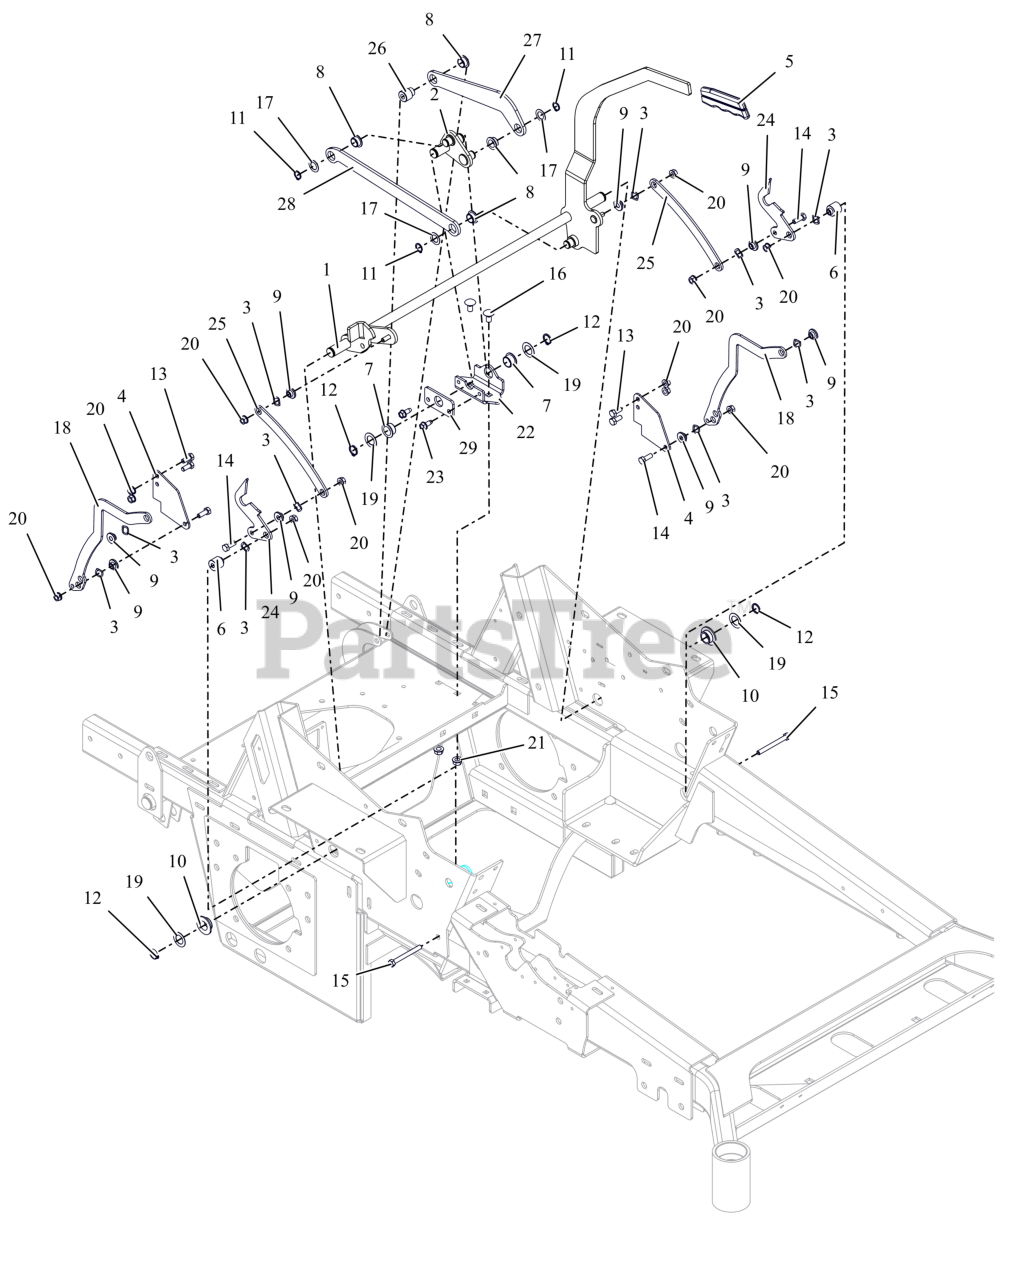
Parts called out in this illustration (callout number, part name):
1	WLDMT, PARKING BRAKE ARM
2	WLDMT, BRAKE ACTIVATION PIVOT
3	WAVE WASHER .531X.781X.125FH
4	BRKT- HTJ SPEED CONTROL -BLACK
5	GRIP, PARKING (GRAY)
6	BUSHING FLANGED - .318X.500X.972X.875
7	BSHG, FLANGE .750 X .875 X .5000 X 1.125
8	BSHG, FLANGE .625 X .750 X .375 X 1.000
9	BSHG-FLG .32X.500X.344X.880
10	BSHG, FLANGED .762 X 1.48 X .44 IGLIDER
11	RG-RTNG-EXT .625X.050
12	RG-RTNG-EXT .689X.078
13	BLT,HEX .31-18X.75 G5 ZCC
14	BLT, HEX .31-18X.875 G5 ZCC
15	BLT, HEX .31-18X3.00 G5 ZCC
16	BLT, RHSN .38-16X.750 G5 ZCC
17	WSHR-THRST .625 X 1.0 X .03
18	LINK- SPEED CONTROL -HTJ (BLK)
19	WSHR-HDND-THRST .758X1.23X.031
20	NUT,LK-CTR-FLG .31-18 GF ZCC
21	NUT-LK-CTR-FLG .375-16 GF ZCC
22	BRKT, BSHG MTG
23	SCR,TAP .312-18X.75 HWH TR ZCC
24	BRKT, BRAKE - RTN (BLACK)
25	BRKT, LINK - BREAK RTN (BLACK)
27	LINK, BRAKE ACTIVATION REAR
28	LINK, BRAKE ACTIVATING FRONT
29	PLATE, BSHG MOUNTING
